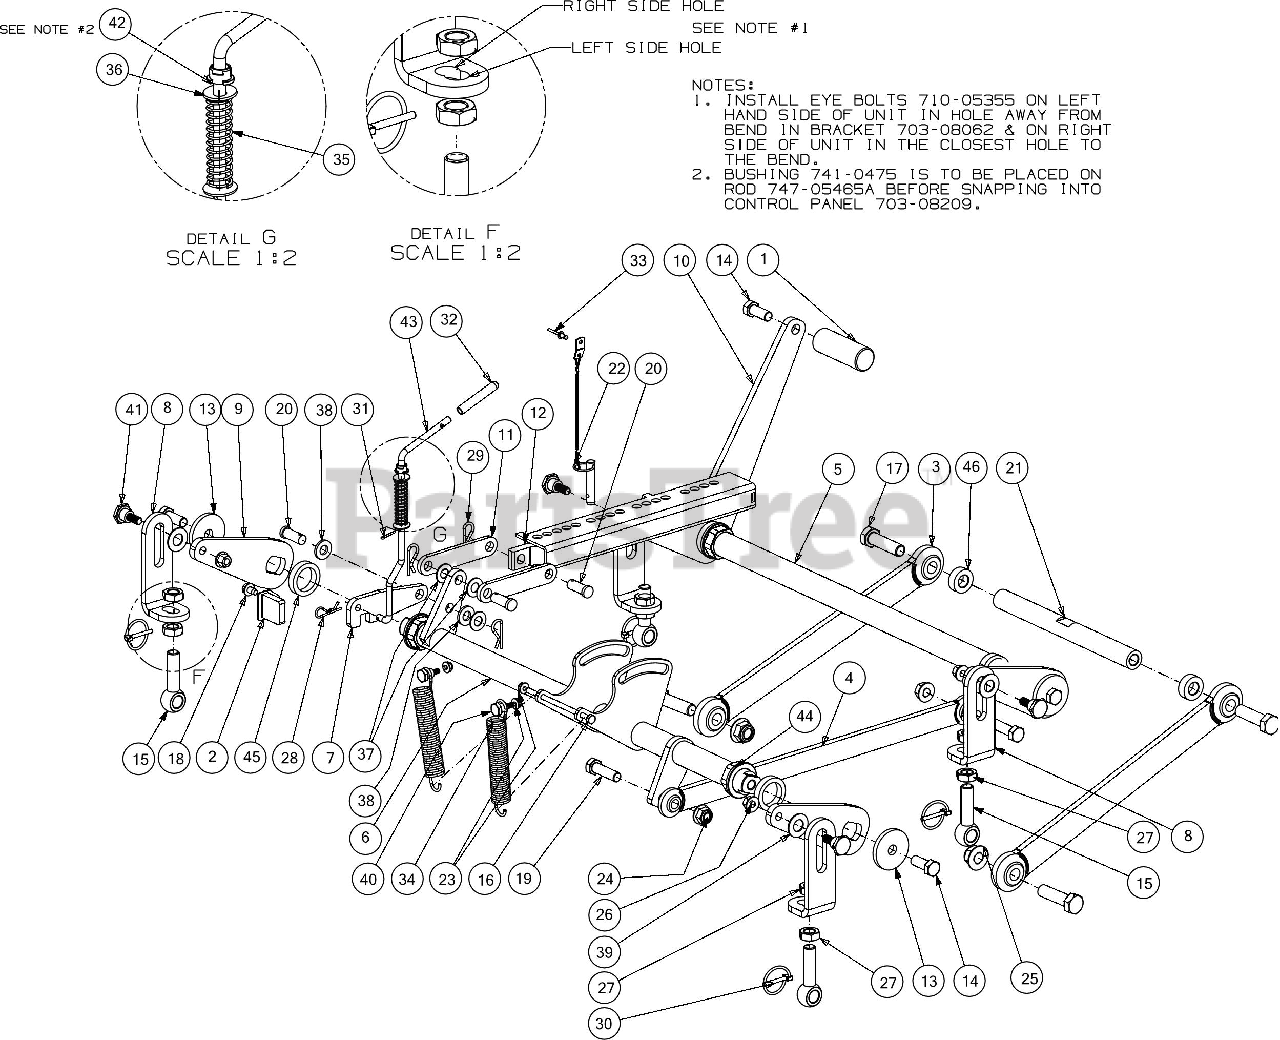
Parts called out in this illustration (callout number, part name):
1	DECK LIFT PEDAL
2	LIFT LOCK MOUNT
3	DECK FRONT ROD ASSEMBLY
4	DECK LIFT ARM ASSEMBLY
5	FRONT DECK LIFT SHAFT
6	DECK LIFT SHAFT
7	LOCK LATCH BRACKET
8	DECK LIFT ARM
9	DECK LIFT BELLCRANK
10	DECK LIFT PEDAL
11	DECK LIFT LINK
12	DECK LIFT LINK
13	FLAT WASHER
14	SCREW 1/2-13 X 1.25 GR5
15	BOLT 5/8-16 X 2.63
16	SCREW 1/4-20 X 5.00 GR5
17	SCREW 5/8-11 X 2.25 GR5
18	SCREW 5/16-18 x .500
19	BOLT 1/2-13X1.75 GR5
20	CLEVIS PIN .500 X 1.25
21	FRONT LIFT SHAFT
22	DETENT PIN
23	FLANGE LOCK NUT
25	FLANGE LOCK NUT
26	NUT-CTRLCK FLG HEX
27	HEX NUT
28	INTERNAL COTTER PIN
29	COTTER PIN
31	COTTER PIN 3/32
33	FULL TUBULAR RIVET
34	EXTENSION SPRING
35	COMPRESSION SPRING .656 ODX 2.445"
36	BELL WASHER .337 X.867 X .057
37	FLAT WASHER .510 X 1.00 X .060
38	FLAT WASHER .510 X 1.000 X .125
39	FLAT WASHER NYLON 5/8
40	SHOULDER SCREW .437X.50 1/4-20
41	SHOULDER SCREW .625 X .442 X 3/8-16
42	BUSHING .380 ID
43	LIFT LATCH LOCK ROD
44	FLANGE BEARING
